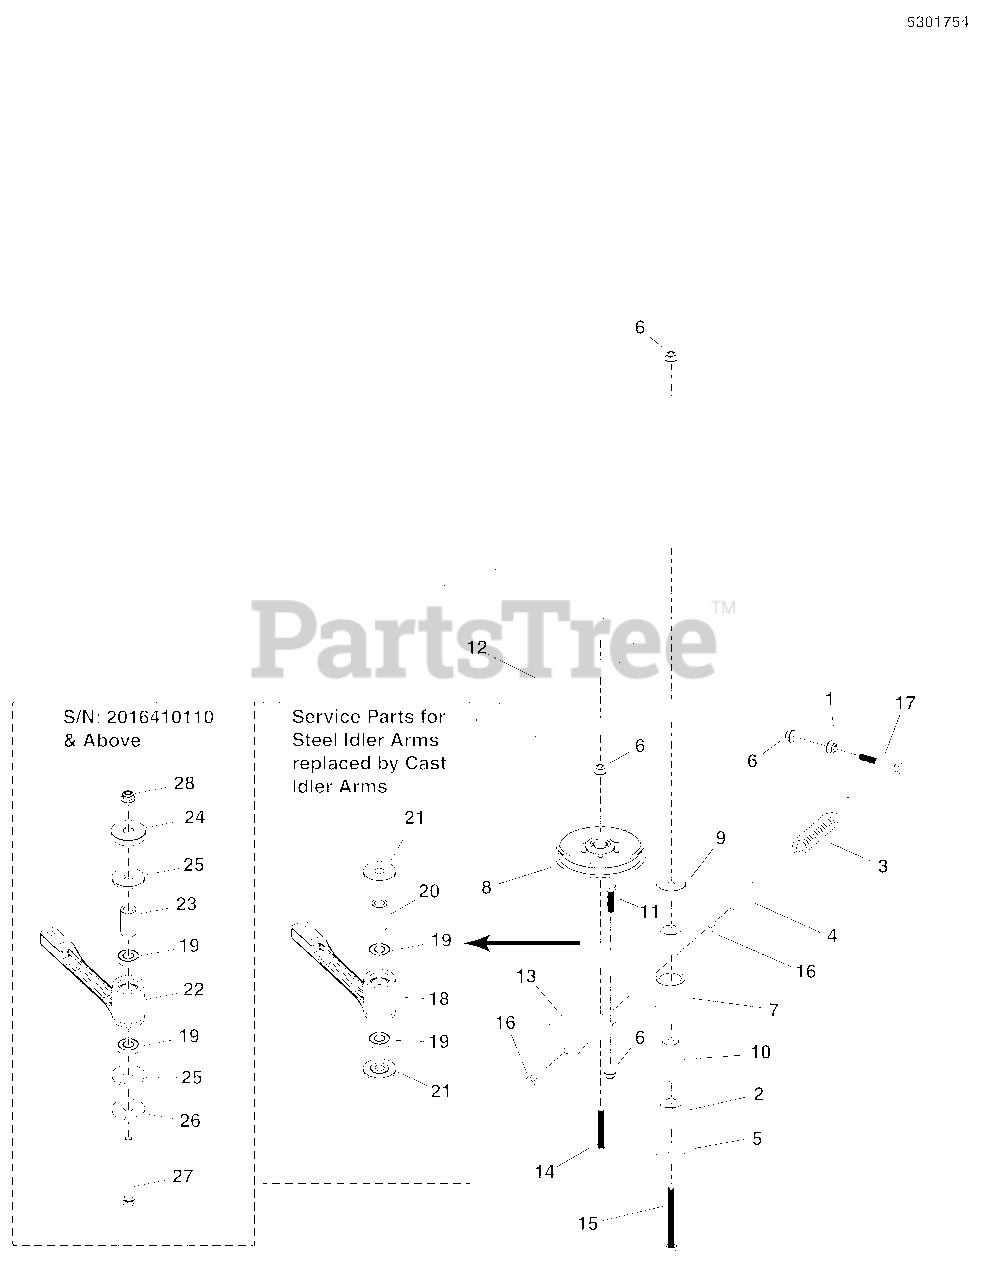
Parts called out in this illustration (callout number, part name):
1	NUT, 3/8-16 HEX SERRATED FLANGE
2	BUSHING, BRASS, 1.25X1X1.25
3	SPRING, EXTENSION, SWIVEL END
4	EYE BOLT, 3/8-16 X 5, 2.88THRD, 1EYE, CZ
5	WASHER, .41 X 1.75 X .14
6	NUT, 3/8-16 HEX NYLOCK FLANGE
8	PULLEY-IDLER, 5.00OD, .385ID, .75W, STL
9	SPACER, .39 X 1.75 X .63, YZ
10	SPACER, .39 X 1.000 X 2.55, SS
11	BOLT, 3/8-16 X 1-1/2" GD5 CZ
12	BELT, HB SEC, 81.2EL
13	PLATE, IDLER ARM ADAPTER - RED
13	PLATE, IDLER ARM ADAPTER - BLK
14	BOLT, 3/8-16 X 2-1/2" GD5 CZ
15	BOLT, 3/8-16 X 4" GD5 CZ
16	NUT, 3/8-16 HEX
17	BOLT, 3/8-16 X 2, GD5, CZ
18	ASSM, IDLER ARM, PUMP DRIVE
19	BEARING, BALL, AXLE
20	SPACER, .39 X .88 X 1.53, CZ
21	SPACER, IDLER ARM, T-STYLE, CZ
22	ASSM, IDLER ARM, PUMP DRIVE, 1/2ID, CAST
23	SPACER, .52 X .84 X 1.53, PM
24	SPACER, .52 X 1.75 X .63, CZ
25	SPACER, IDLER ARM, 1/2, PM
26	WASHER, .52 X 1.75 X .14, CZ
27	BOLT, 1/2-13 X 4-1/2 GD5 YZ
28	NUT, Hex Flange, Nylock, 1/2-13
